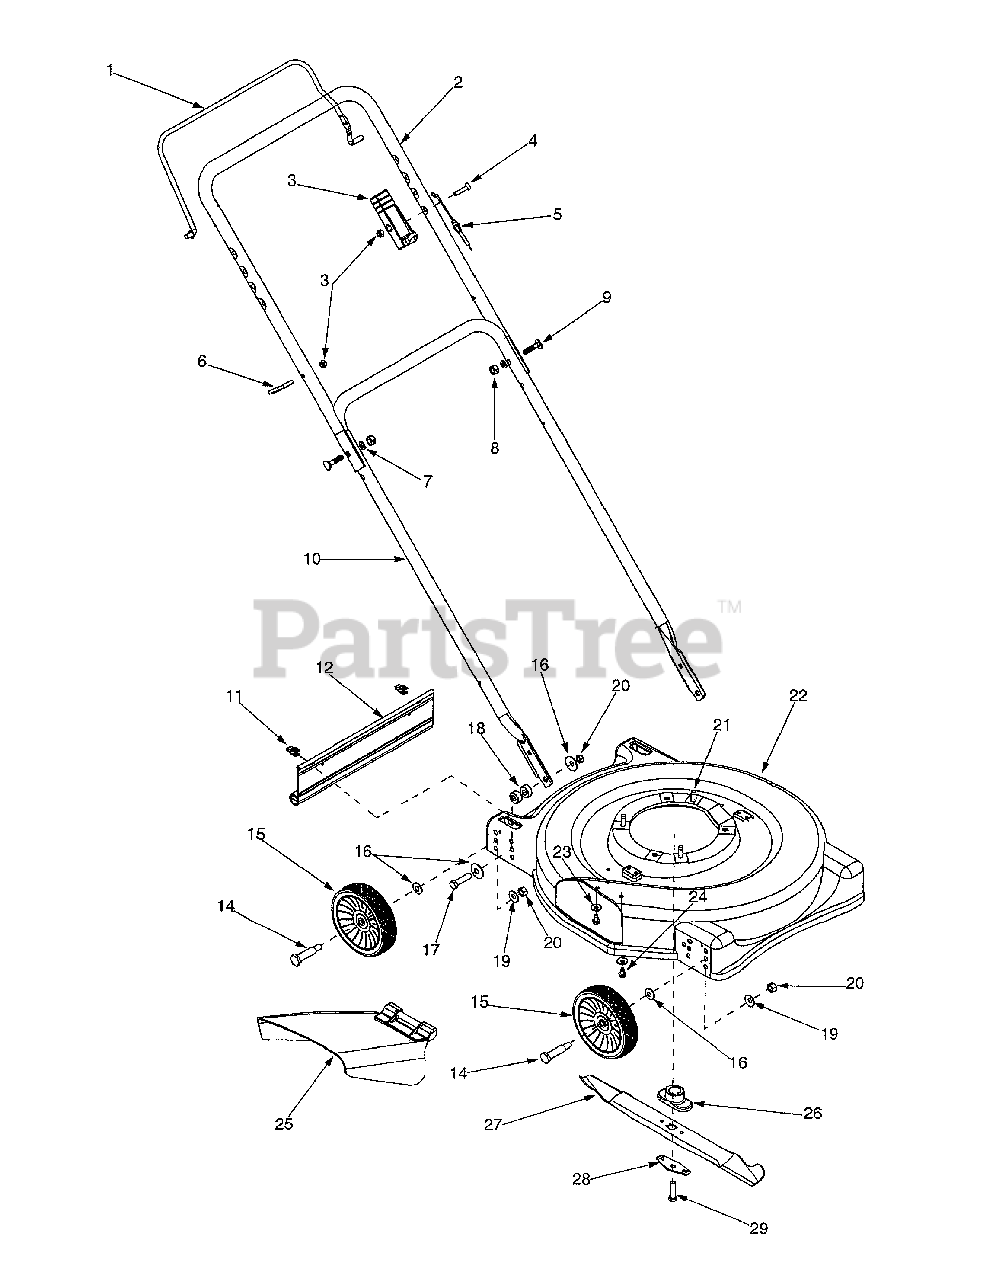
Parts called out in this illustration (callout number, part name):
4	Oval C-Sunk Screw
5	Control Cable
6	Rope Guide
7	Lock Washer 5/16"
8	Hex Nut 5/16-18
9	Carriage Bolt 5/16-18 x 1"
11	Hinge Clip
12	Rear Trail Shield
14	Axle Bolt
15	Wheel Assembly
16	Bell Washer .380 ID x .88"
17	Hex Bolt 3/8-24 x 1.5
18	Spacer .391" ID x .850" OD
19	Bell Washer .39 ID x 1.13 OD
20	Hex Nut 3/8-16
21	Hex Washer Screw 3/8-16 x 1"
24	Hex Washer Screw 1/4-20 x .5"
25	Chute Deflector Assembly
26	Blade Adapter
27	Blade
28	Bell Blade Support
29	Hex Bolt 3/8-24 x 1.5"
